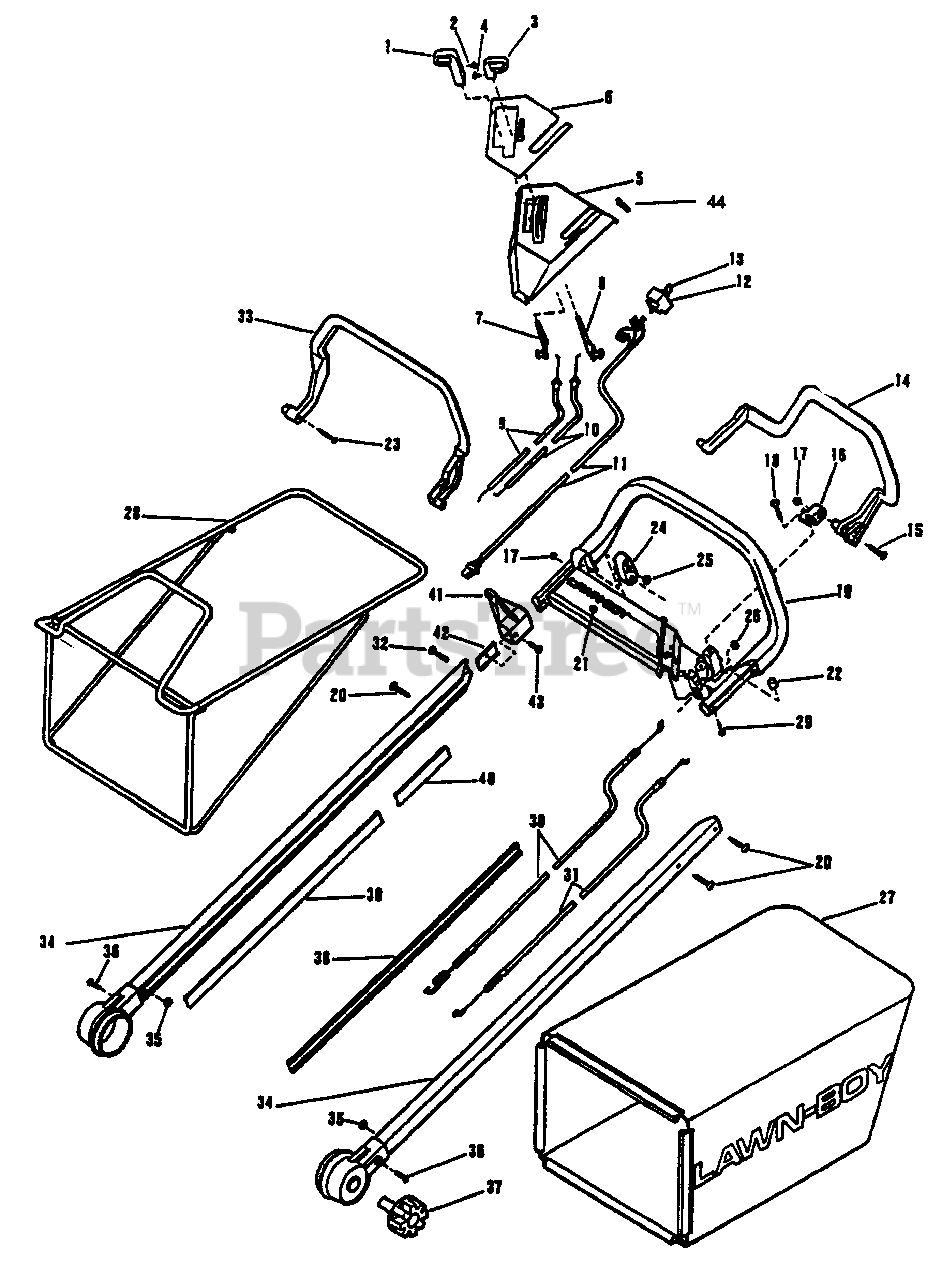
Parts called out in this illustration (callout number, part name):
1	Knob Assy-Gear Select (Inc. 2)
2	Set Screw
3	Knob Assy-Throttle (Inc. 4)
4	Set Screw
5	Upper Cvr Assy (Inc. 6)
6	Plate
7	Gear Select Lever
8	Throttle Lever
9	Cable Assembly-Gear Select
10	Cable Assembly-Throttle
11	Wire Harness (680503)
12	Switch Assembly (680503)
13	Ignition Key (680503)
14	Self propelled Bail
15	Screw
16	Bail Pivot
17	Nut
18	Screw
19	Handle & Decal Assy (Inc. 20-21)
20	Screw-Thread Forming
21	Decal-Lawn-Boy
22	Bumper
23	Screw
24	Bail Block
25	Nut
26	Nut-Self-propelled Cable
28	Frame
29	Screw
30	Cable Assembly-Self-propelled
31	Cable Assembly-Engine Brake
32	Screw
33	Engine Brake Bail
34	Handle Shaft Assy (Inc. 35-36)
35	Nut
36	Screw
37	Knob-Handle Mounting
38	Handle Insert-Cable Side
39	Handle Insert
40	Handle Insert
41	Rope Guide
42	Nut Plate
43	Screw
44	Plug (680549)
